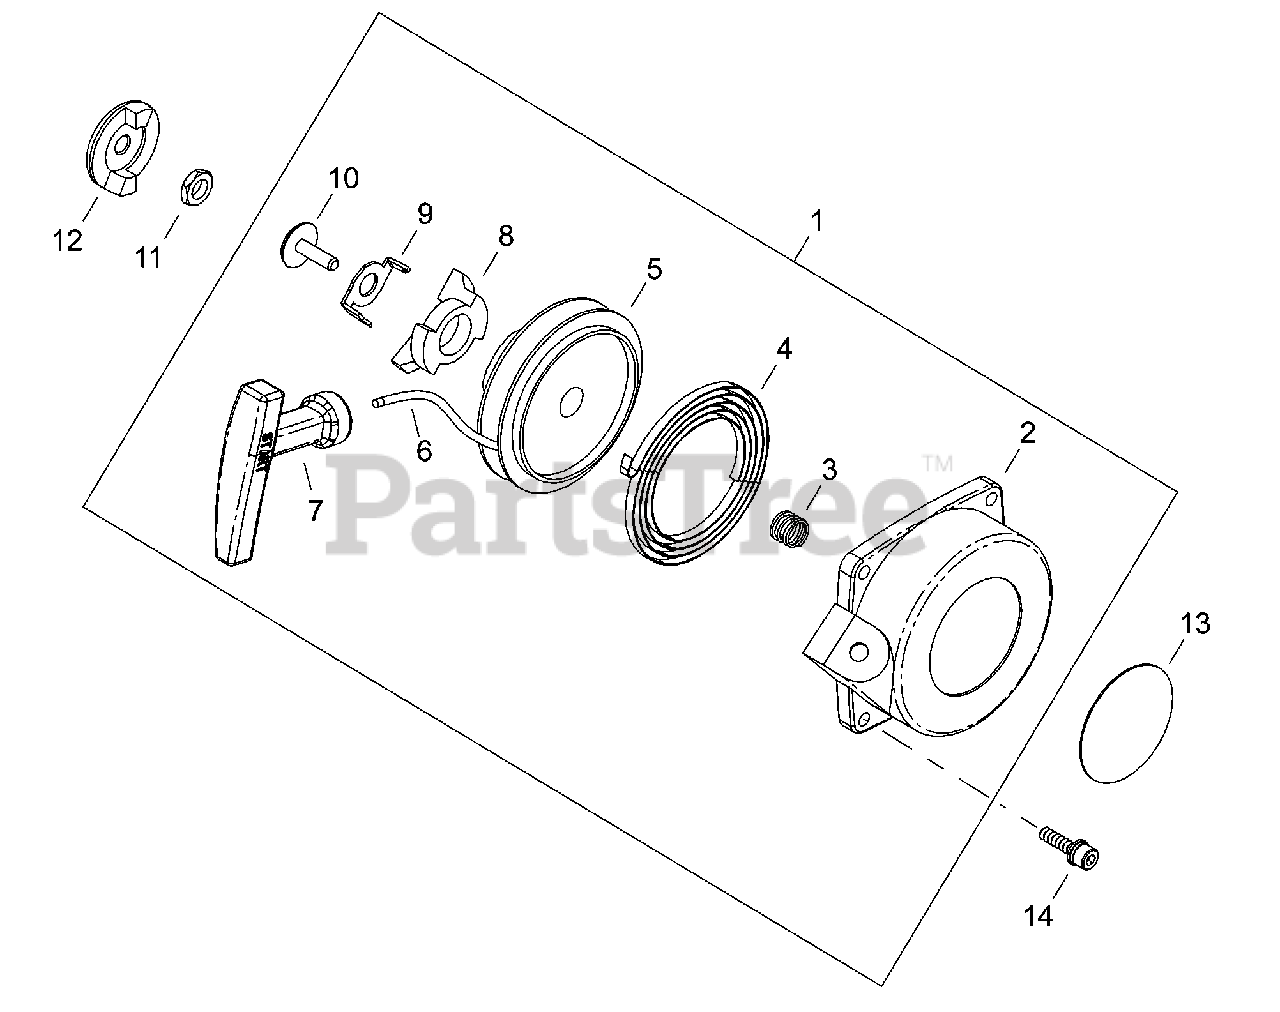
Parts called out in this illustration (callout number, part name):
1	STARTER ASSY
2	CASE, STARTER
3	SPRING, BRAKE
4	SPRING, REWIND
5	REEL, ROPE
6	ROPE, STARTER
7	GRIP, STARTER
8	PAWL, STARTER
9	RETAINER
10	SCREW
11	NUT - 8
12	REEL, ROPE
13	LABEL - SHINDAIWA PROFESSIONAL
14	SCREW - 5X16
